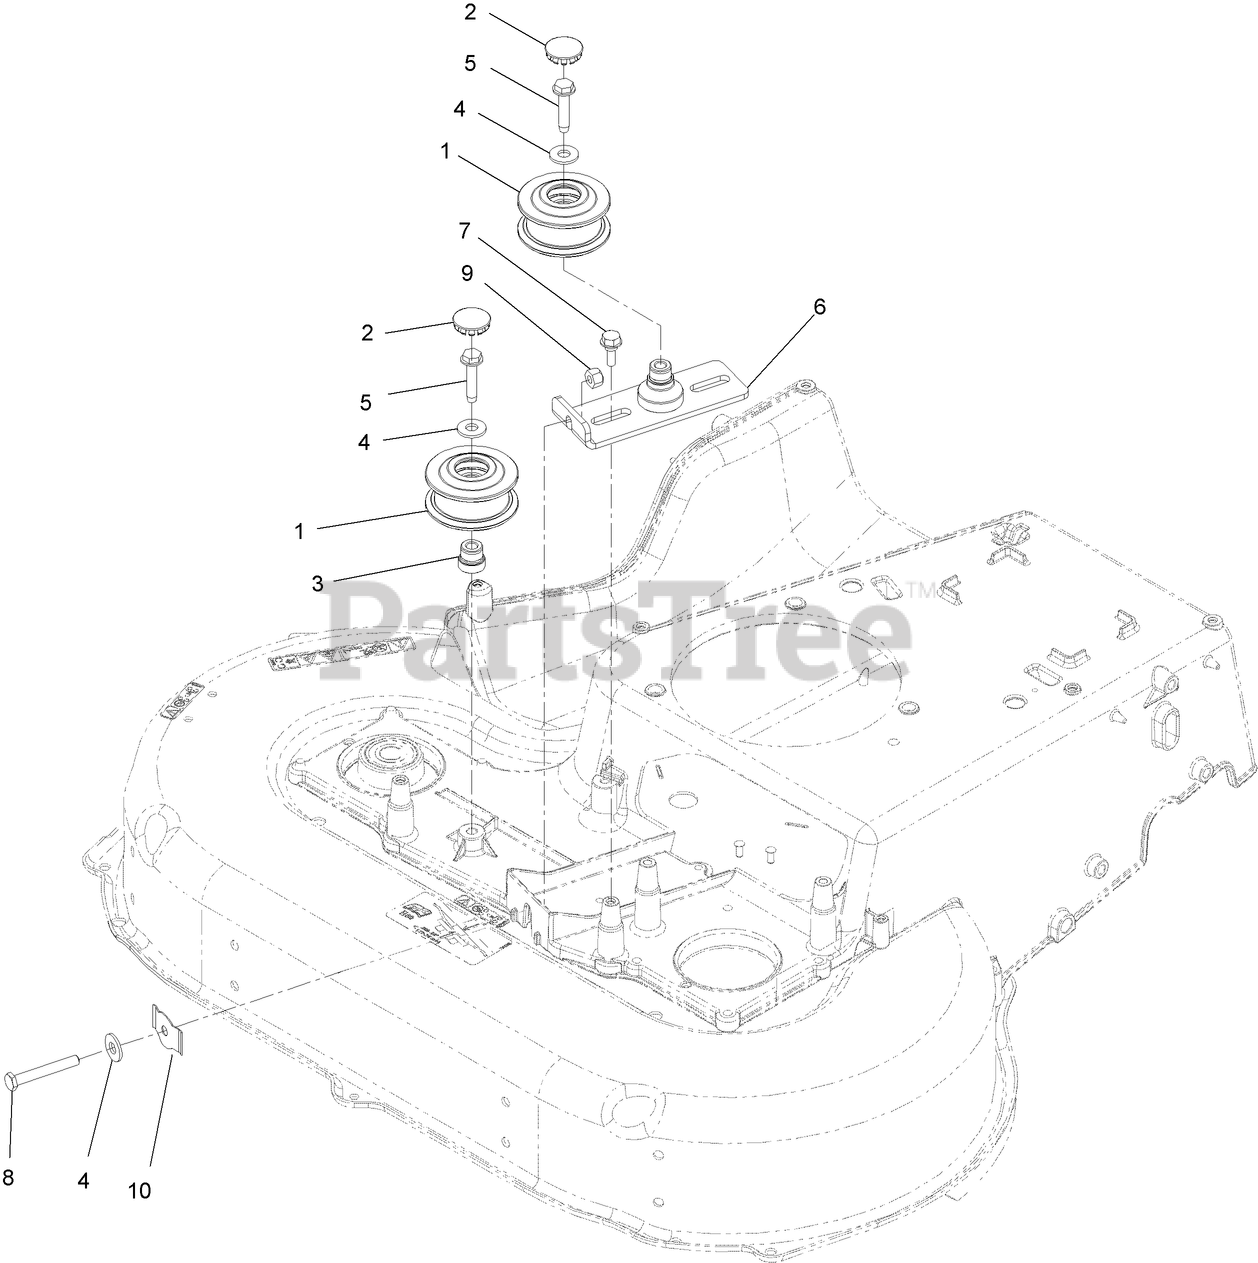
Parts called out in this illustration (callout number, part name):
1	PULLEY-IDLER, FLAT
2	PLUG-BUTTON
3	ADAPTER-BORE
4	WASHER-FLAT
6	BRACKET-IDLER
7	SCREW-SHOULDER,HWH
8	BOLT-TAP, HH
9	NUT-LOCK, NI
10	SPRING-FLAT
